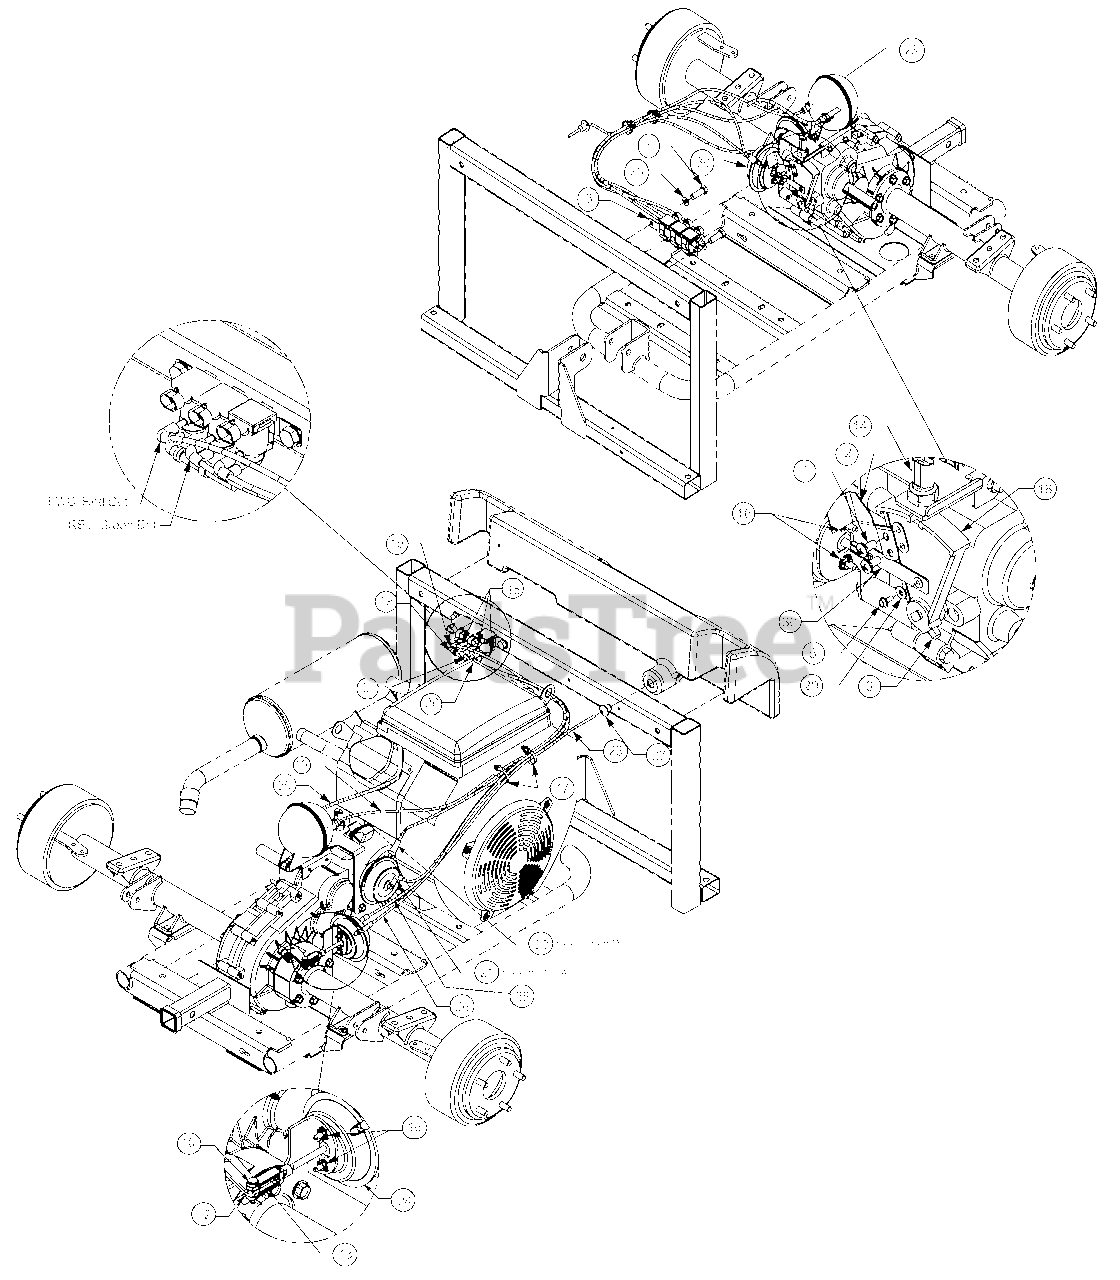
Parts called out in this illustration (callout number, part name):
2	Bracket, Shift
3	Bracket, Vac Relay
4	Screw, 1/4-20 x.5
5	Screw, Hex. #8 - 18 .375
6	Screw, Set, 5/16-24 x .50 LG
9	Screw, 1/4-14 x .625 Hex
10	Pin, Clevis .312 OD x 1.0
12	Pin, Cotter 3/32 x .750
13	Yoke, 1/4-28
14	Switch, Neutral
15	Solenoid, Kit Vacuum Actuator
16	Self Threading Nut
17	Cable Tie
18	Arm, Shift
19	Hose
20	Hose, Manifold Vacuum
21	Hose, Actuator Vacuum
22	Hose, Actuator Vacuum
23	Reservoir, Air
24	Actuator, Vac Differential Lock
25	Hose, Vac Differential Lock, Vent
26	Hose, Vac Differential Lock Supply
27	Grommet, .58 x .25
28	Flat Washer, .330 x .687 x .030
29	Flat, Washer, .188 x .437 x .042
30	Actuator, Vacuum Shift
